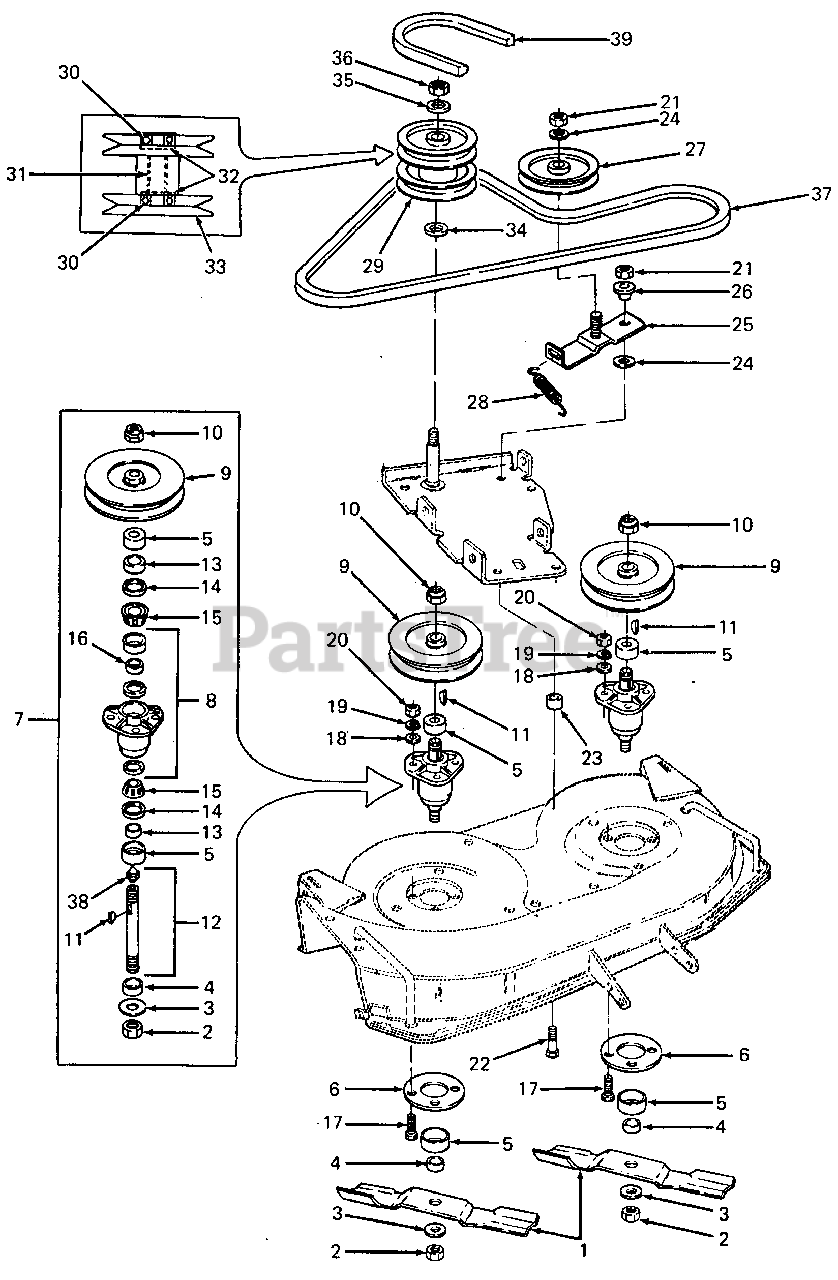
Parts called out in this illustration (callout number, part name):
1	Blade, Low Lift, 19.38 Lg
2	Nut, Hex, 3/4-16 GR8
3	Washer, Flat, .781 X 2.0 X .105 Thk HDN
4	Spacer, Blade
5	Cup, Spindle HDN
6	Plate, Spindle Mounting
7	Spindle Service Kit
8	Housing, Spindle w/Cups
9	4L V-Pulley, 4.62 OD X .75 ID
10	Nut, Hex Jam, 3/4-16
11	Key, #91 Woodruff, 1/4 X 3/4 HDN
12	Kit, Shaft w/Seal
13	Spacer, .755 X 1.25 X .44 Lg
14	Seal, Oil, 1.25 X 1.874 X .25
15	Cone, Bearing
16	Spacer, Bearing
17	Screw, Hex Cap, 3/8-16 X 1.25 GR5
18	Washer, Flat, .378 X 1.0 X .127 Thk
19	Washer, Lock, 3/8 Dia
20	Nut, Hex, 3/8-16 GR5
21	L-Nut, Hex Cent., 3/8-16 GR5
22	Bolt, Short Neck Carr, 3/8-16 X 1.5 Lg GR5
23	Spacer, .390/.400 ID X .75 OD X .44 Lg
24	Washer, Flat, .385 X .88 X .06 Thk HDN
25	Bracket, Idler
26	Spacer, Shld
27	Pulley, Flat Idler
28	Spring, Extension, .75 OD X 3.38 Lg
29	Pulley Assy, Double
30	Bearing, Ball, .62 ID X 1.38 OD X .44 Thk
31	Spacer, Pulley, .64 ID X .81 OD X 2.25 Lg
32	Snap Ring, Internal
33	Pulley, Double
34	Washer, Flat, .625 ID X 1.0 OD X .06 Thk HDN
35	Washer, Flat, .510 ID X 1.12 OD X .100 Thk
36	Nut, Hex Patch Jam, 1/2-20
37	V-Belt, 1/2 X 60" Lg - A Full
38	Fitting, Lube, 3/16
39	V-Belt, PTO Drive, 1/2 X 58.5
